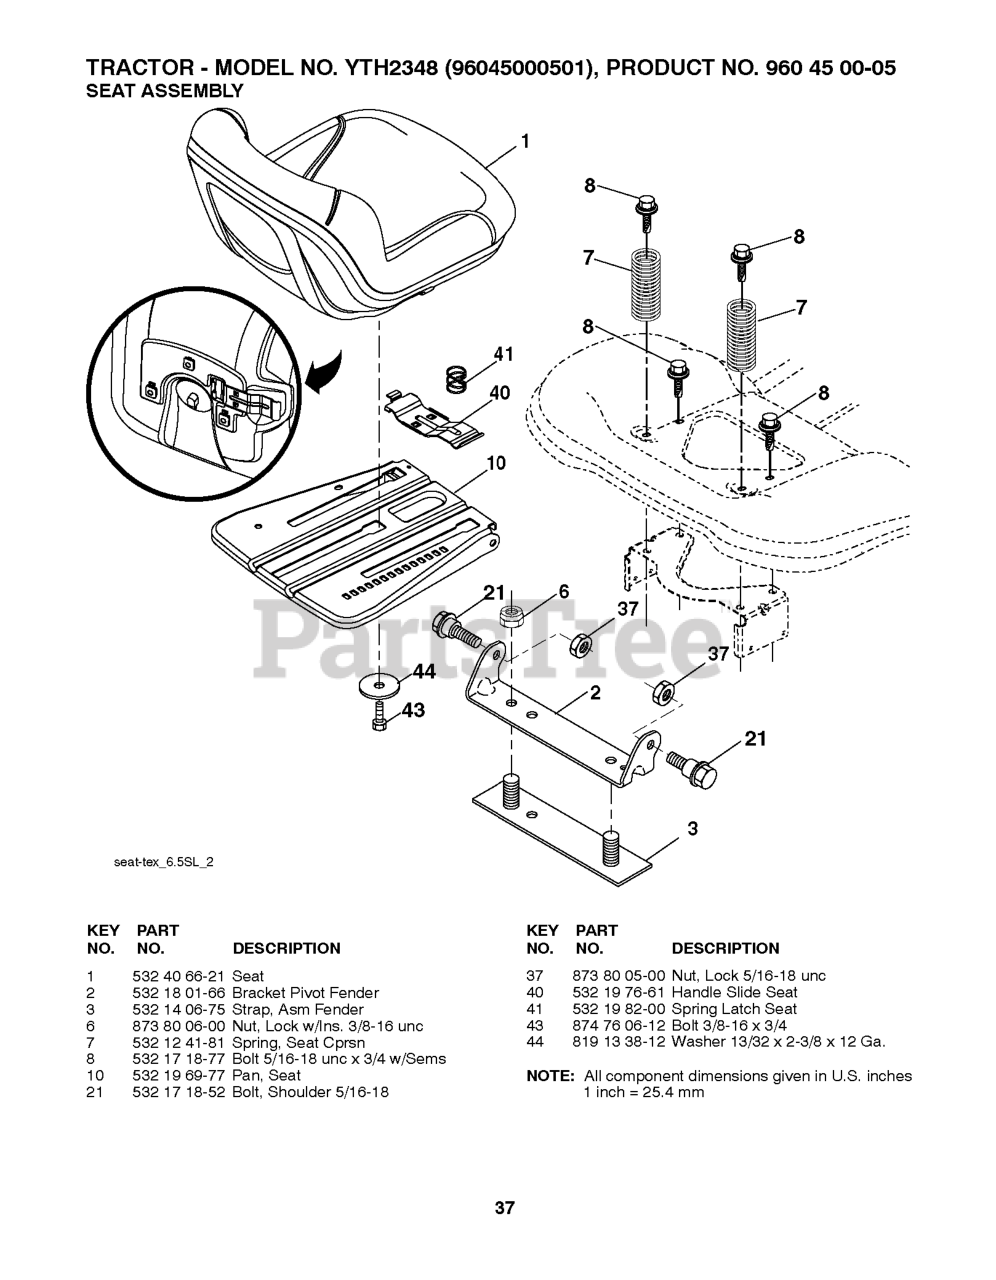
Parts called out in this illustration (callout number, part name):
1	SEAT - GREY
2	BRKT.PIVOT.FENDER
3	STRAP
6	NUT
7	SPRING COMPRESSION
8	BOLT.5/16-18UNCX3/4 W/SEMS.BLK
10	PAN.ASM.SEAT.3PT
21	BOLT.SHOULDER.5/16-18
37	NUT.71038.31-18.HEX.NYLOCK
40	HANDLE.SLIDE.SEAT.TEX.BLACK
41	SPRING.LATCH.SEAT.TEX
44	WASHER 13/32 X 2-3/8 X 12GA
